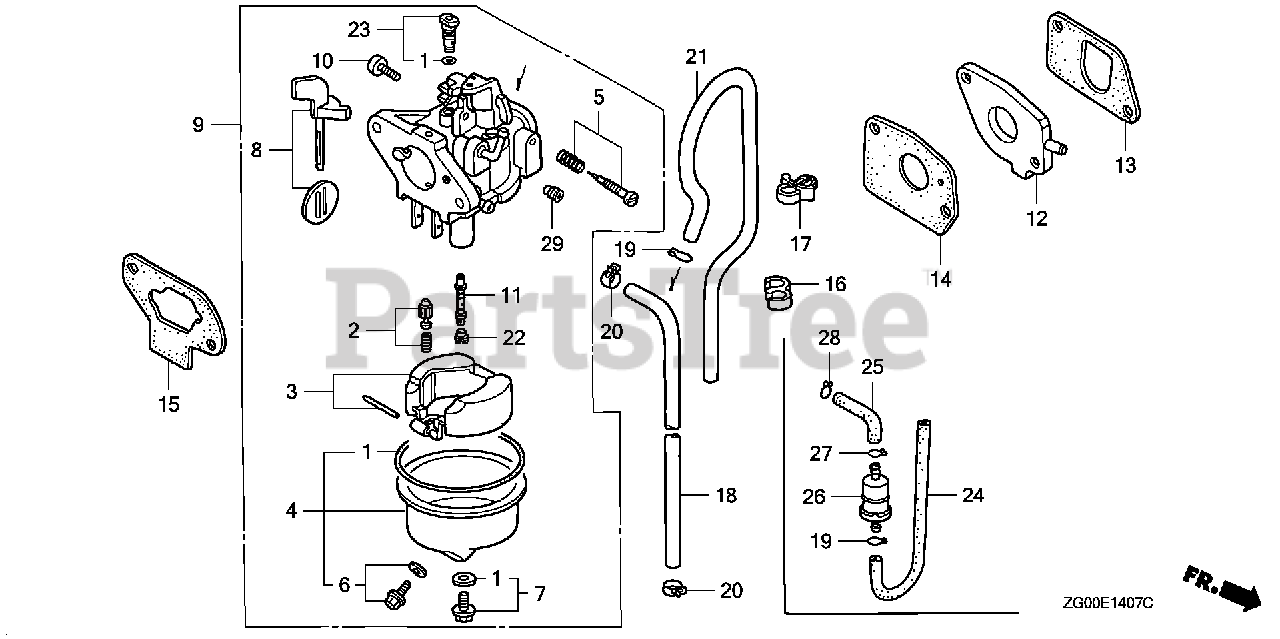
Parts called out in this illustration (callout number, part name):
1	GASKET SET
2	VALVE SET, FLOAT
4	CHAMBER SET, FLOAT
5	SCREW SET, PILOT
6	SCREW SET, DRAIN
7	SCREW SET
9	CARBURETOR ASSY. (BF03B D)
10	SCREW, THROTTLE STOP
11	NOZZLE, MAIN
12	INSULATOR, CARBURETOR
13	GASKET, INSULATOR
14	GASKET, CARBURETOR
15	GASKET, AIR CLEANER
16	CLIP, IGNITION WIRE
18	BULK HOSE, FUEL (4.5X3000) (4.5X400)
19	CLIP, TUBE (B8)
20	CLAMP, TUBE (D8.5)
22	JET, MAIN (#50) Use from Engine SN BF03B D.
22	JET, MAIN (#52)
22	JET, MAIN (#55) Use up to Engine SN BF03B C.
22	JET, MAIN (#58) (CARBURETOR NO.)
23	JET SET, PILOT (#35)
24	TUBE A, AIR VENT
25	TUBE B, AIR VENT
26	FILTER, FUEL
27	CLIP, TUBE (B10)
28	CLIP, TUBE (C9)
